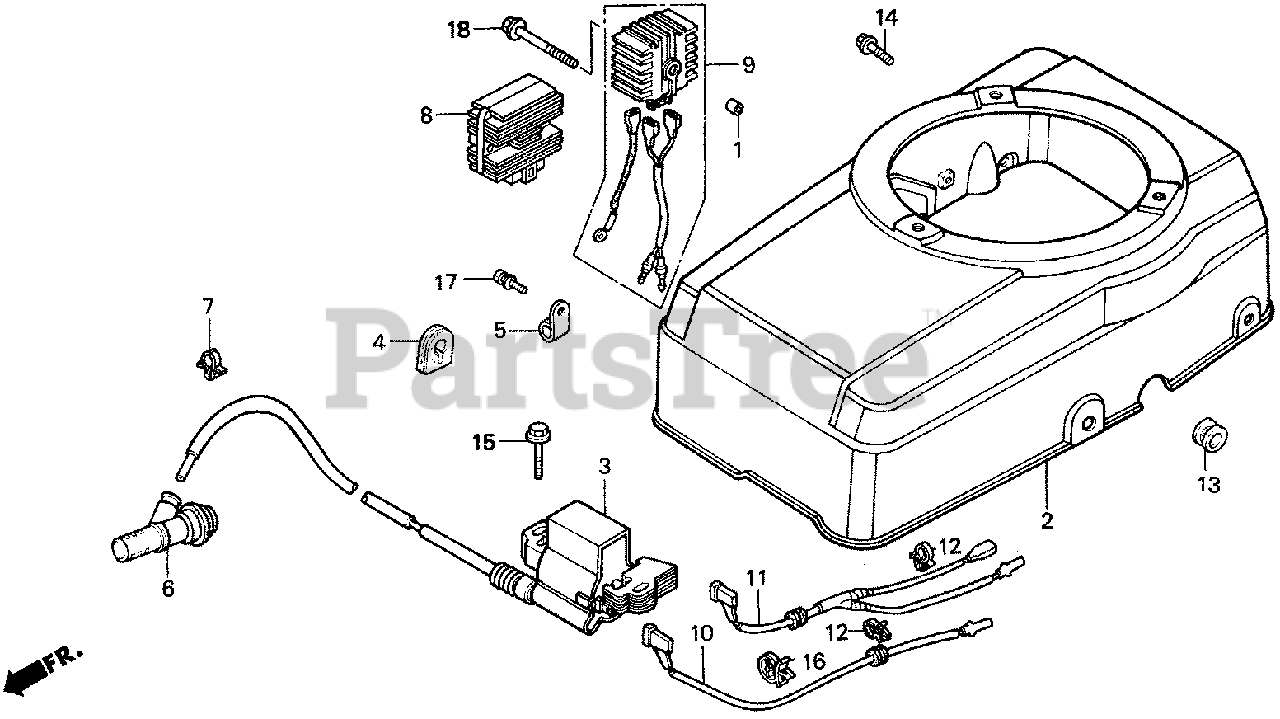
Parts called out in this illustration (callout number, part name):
1	SPACER, AIR CLEANER ELBOW
2	COVER, FAN
3	COIL ASSY., IGNITION (Honda Code 2106441). (NOT AVAILABLE)
4	GROMMET, IGNITION
5	CLAMP, IGNITION WIRE
6	CAP ASSY., NOISE SUPPRESSOR
9	RECTIFIER ASSY., SILICON
11	WIRE, STOP SWITCH
12	HOLDER, STOP SWITCH WIRE
13	GROMMET, WIRE
14	BOLT, FLANGE (6X12) (CT200)
15	BOLT, FLANGE (6X28)
16	CLIP, WIRE HARNESS
17	SCREW-WASHER (5X12)
18	BOLT, FLANGE (6X40)
